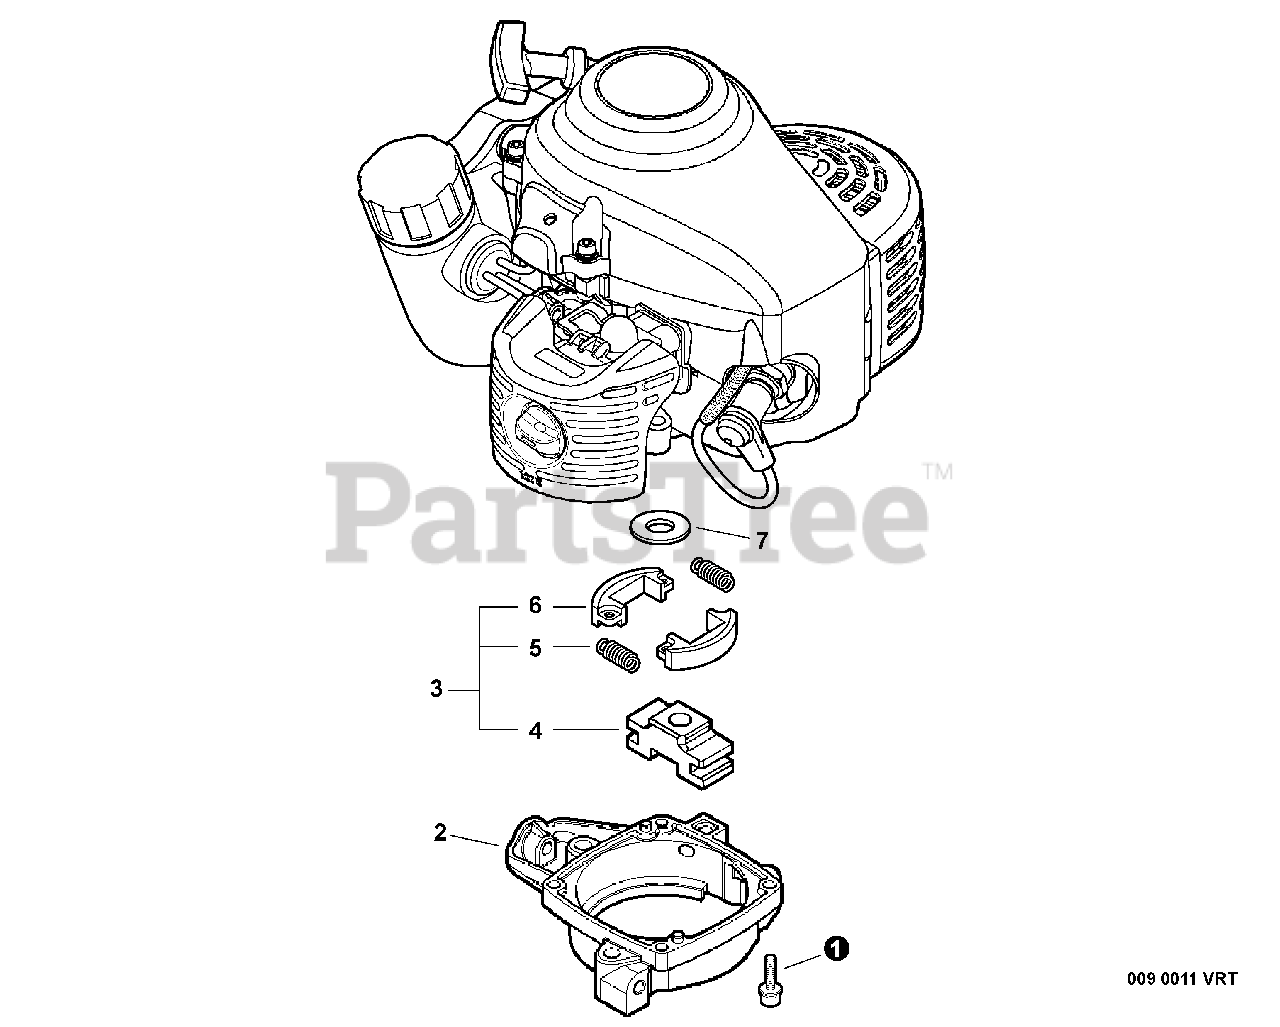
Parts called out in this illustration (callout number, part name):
1	BOLT 4×16
2	CASE, CLUTCH
3	CLUTCH ASSY
4	HUB, CLUTCH
5	SPRING, CLUTCH
6	SHOE, CLUTCH
7	WASHER 8
